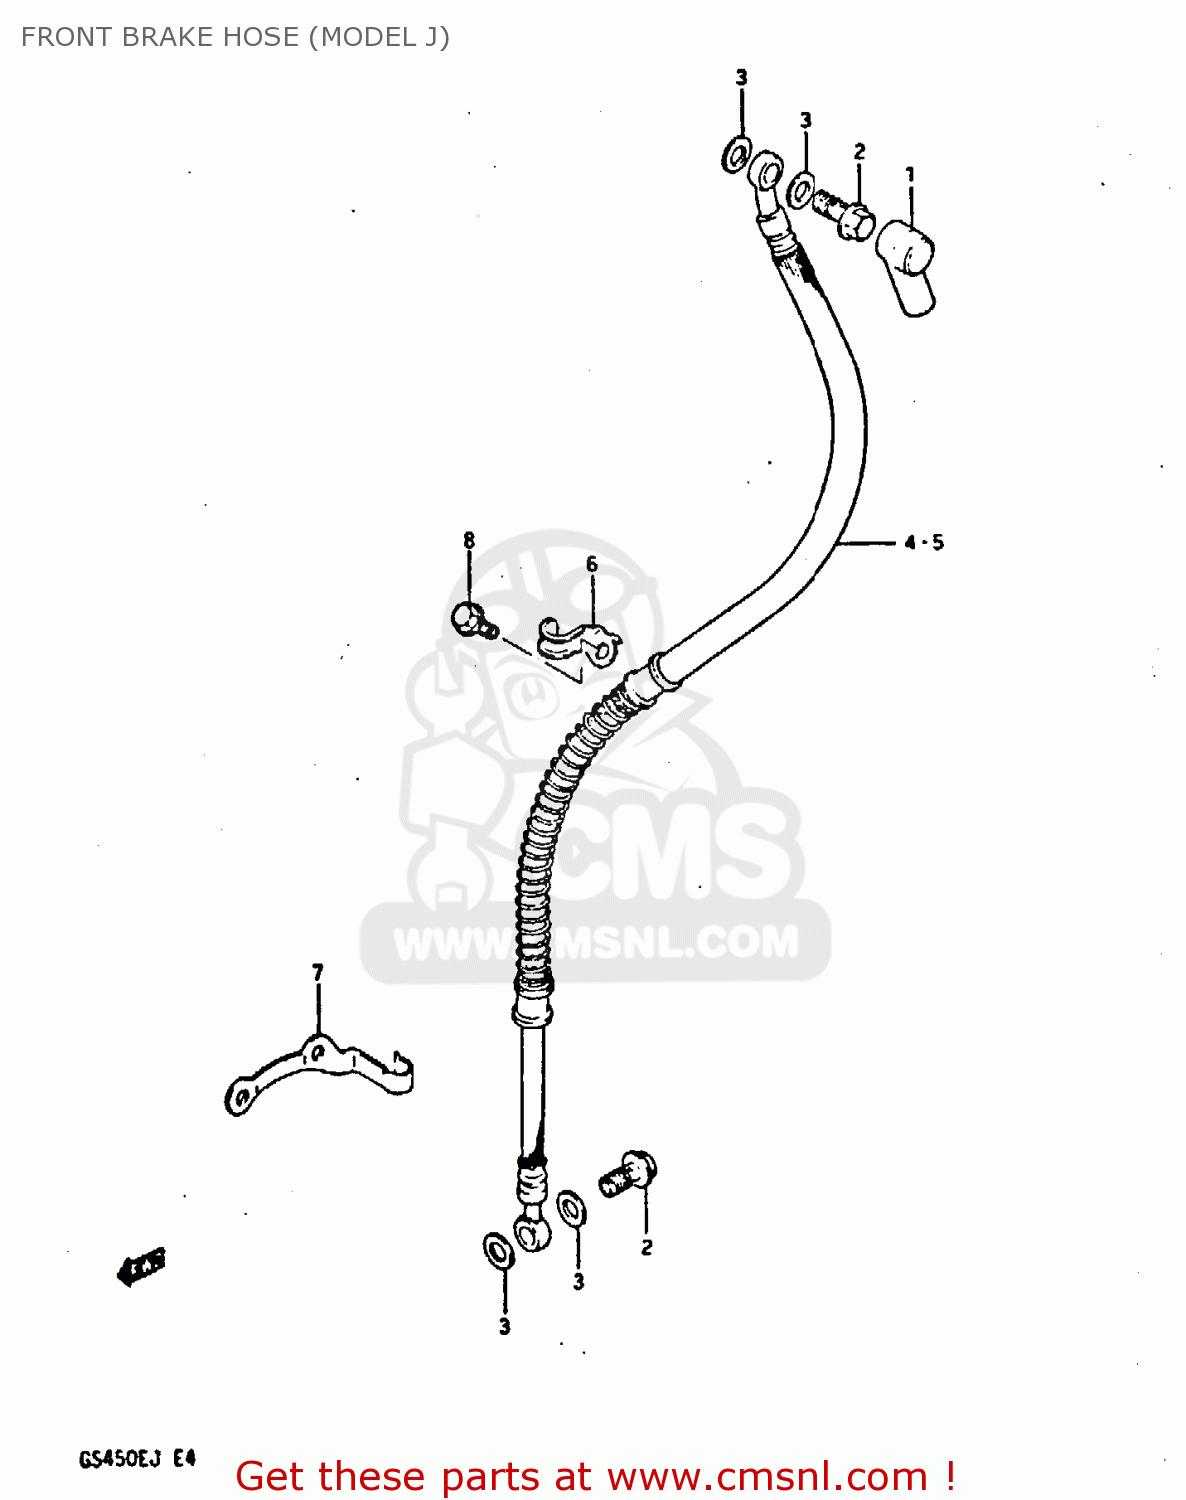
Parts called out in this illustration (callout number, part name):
1	BOOT,MASTER CYLINDER
2	BOLT UNION
3	WASHER(10X15X1.5)
4	HOSE,FR BRAKE
5	HOSE, BRAKE (FLAT HANDLEBAR)
6	GUIDE,BRAKE HOSE NO.3
7	CLAMP, HOSE LH
8	BOLT 6X12
